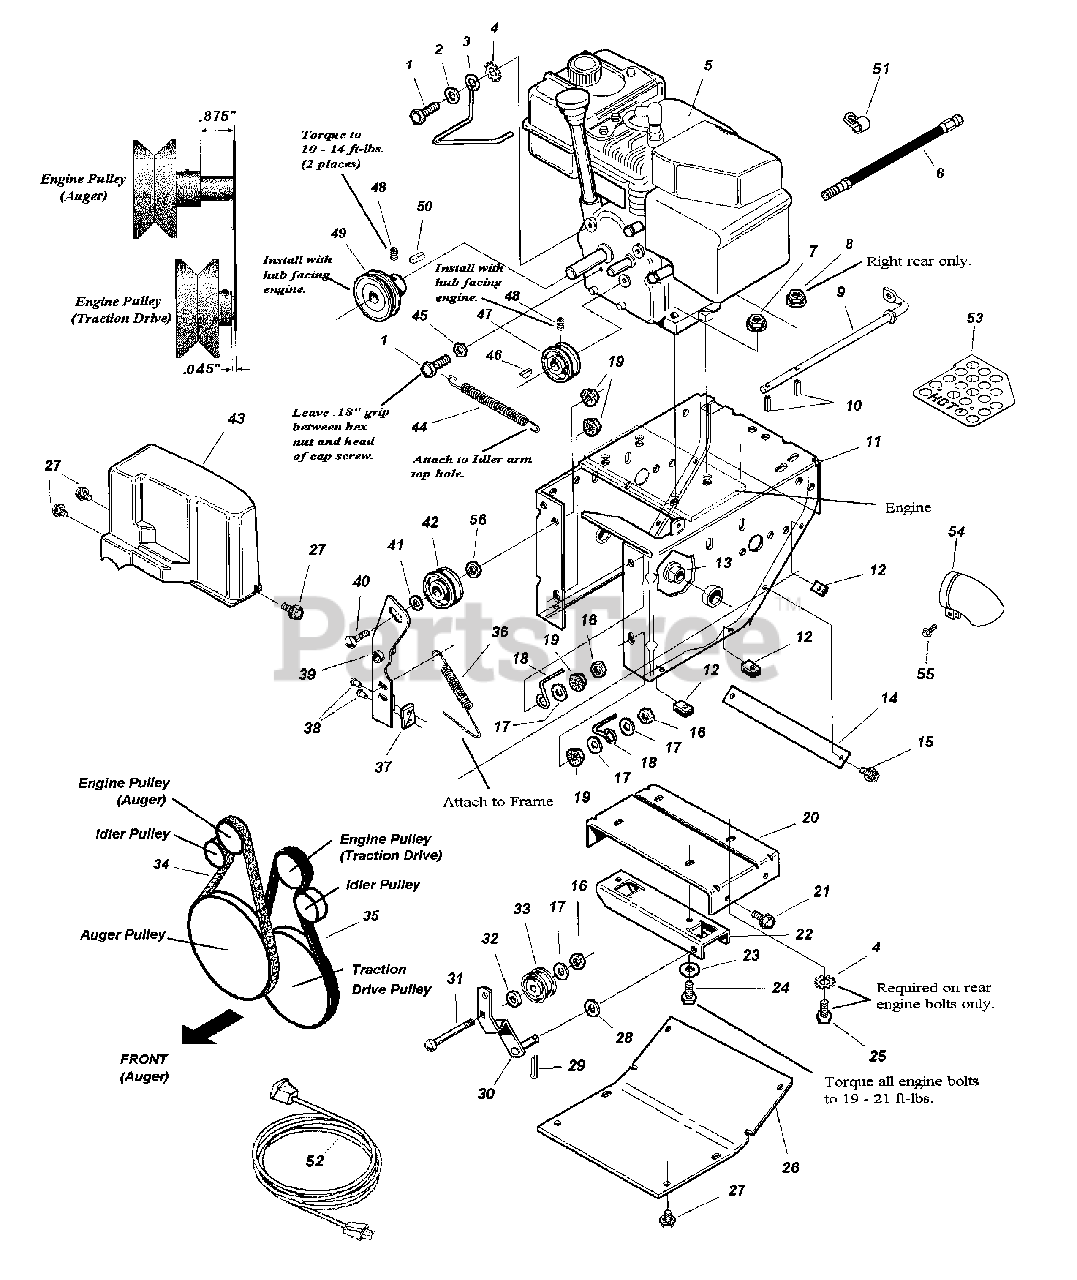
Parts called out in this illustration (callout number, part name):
1	SCREW, 5/16-24 x 1-1/4" Hex Head Cap, GR 5
2	WASHER, 5/16" Flat
3	BELT STOP, Wire
4	LOCKWASHER, 5/16" Exterior Tooth
5	ENGINE, 8HP Intek (Metric) Briggs & Stratton
6	HOSE, Oil Drain
7	NUT, 5/16-18 Hex Flange Lock- small
8	NUT, 5/16-18 Hex Flange Lock
10	ROLL PIN, 3/16 x 3/4"
11	FRAME ASSEMBLY, Intermediate (Orange)
12	SPEED NUT, 1/4-20 U-Type
13	BUSHING, 1.00 long
14	SUPPORT, Tie Bar
15	SCREW, #10-24 x 1/2" Hex Washer Self-Tap
16	JAM NUT, 3/8-16 Hex Center Lock
17	WASHER, 3/8" SAE Flat
18	ROD, Belt Guide
19	NUT, 3/8-16 Hex Nyloc Heavy Thin
20	SUPPORT, Frame
21	SCREW, 5/16-18 x 1/2" Hex Washer Self-Tap
22	SUPPORT, Pivot
23	WASHER, 5/16" Flat
24	SCREW, 5/16-18 x 1-3/4 Hex Head Cap, GR 5
25	SCREW, 5/16-18 x 1-3/4 Hex Head Cap, GR 5
26	COVER, Bottom, Orange
27	SCREW, 1/4-20 x 5/8" Hex Washer Self-Tap
28	WASHER, 7/16" Flat
29	COTTER PIN, 1/8 x 3/4"
30	IDLER ARM ASSEMBLY
31	BOLT, 3/8-16 x 1-1/4" Short Square Neck Carriage
32	SPACER, .377 ID x .75 OD x .312 Long
33	PULLEY, Idler
34	BELT, Auger Drive
35	V-BELT, Traction Drive
36	SPRING, Extension
38	RIVET, Blind
39	ASSEMBLY, Idler Arm w/Brake Pad
40	BOLT, 3/8-16 x 1-3/4 Short Square Neck Carriage, GR 5
41	WASHER, 3/8" Flat (.41 ID x 1.00 OD x .13 Thick)
42	PULLEY, Idler
43	COVER, Belt
44	SPRING, Extension, .562 O.D. x 4.250 Long
45	JAM NUT, 5/16-24 Hex
46	KEY - Hi Pro .125 x .625 HP 504 SAE1035
47	PULLEY, V Groove
48	SET SCREW, 5/16-18 x 5/16" Hex Recess, Cup Point
49	PULLEY, 2.75 OD
50	KEY, 3/16 Square x 1"
51	HARNESS CLIP
52	CORD, Electric Start
53	GUARD, Muffler
54	MUFFLER, Deflector- B&S
55	CAPSCREW, Thread Rolling M4 x 0.7, Briggs p/n 226462
56	NUT, 3/8-16 Hex Flange Lock Two Way, Briggs p/n 810140
